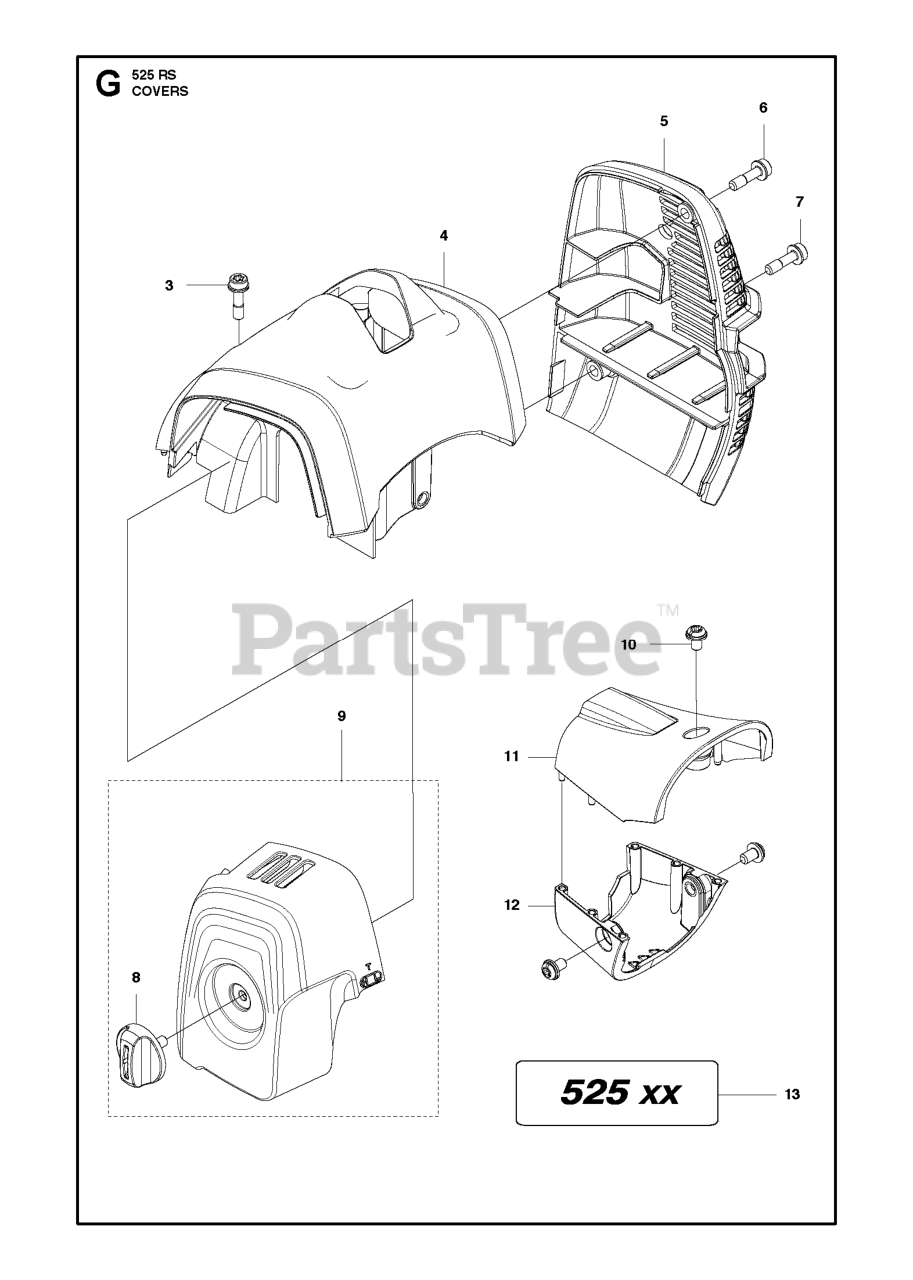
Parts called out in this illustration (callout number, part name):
3	BOLT
4	Cylinder
4	CYLINDER COVER
5	MUFFLER GUARD
6	BOLT
7	BOLT
8	KNOB CLEANER COLOR:GREY
9	FILTER COVER ASSY
11	COVER CLUTCH HOUSING UPPER
12	COVER CLUTCH HOUSING LOWER
